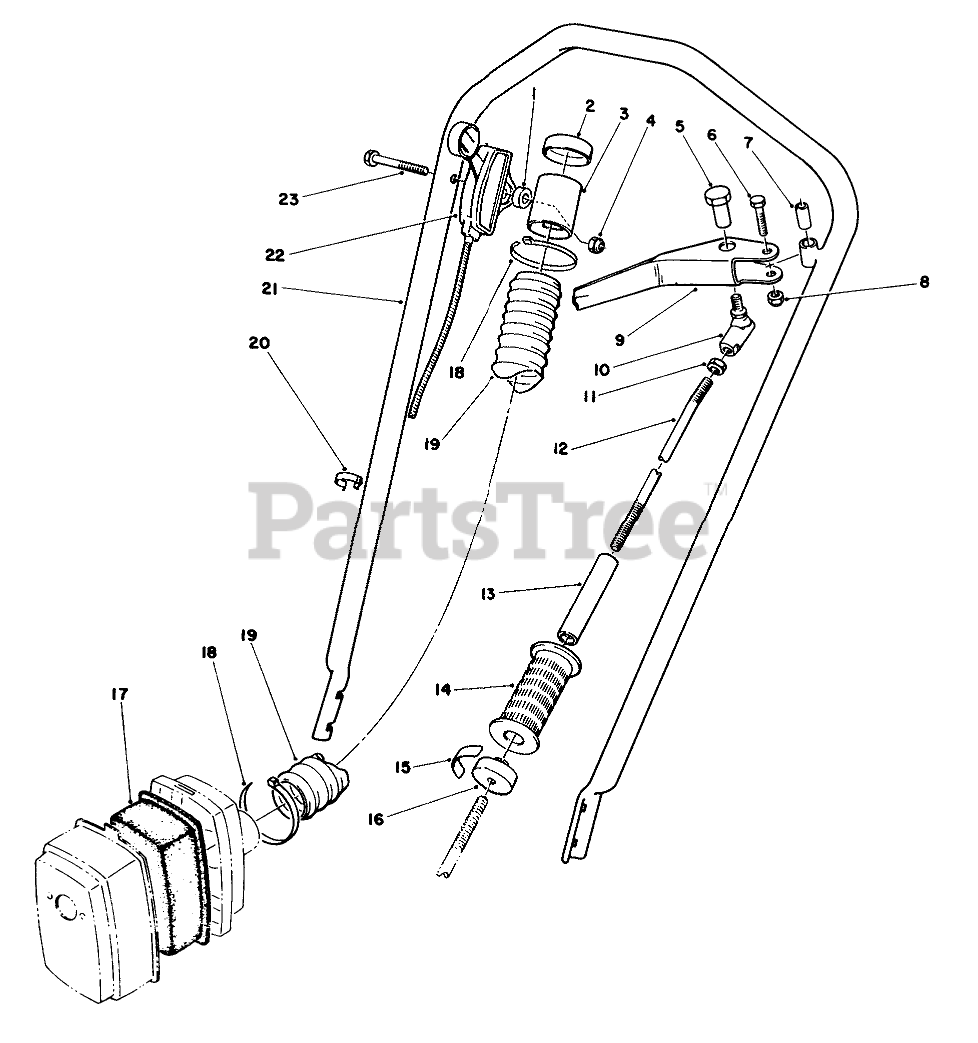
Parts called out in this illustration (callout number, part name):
1	SPACER
2	BLACK CAPLUG
3	AIR CLNR HOSE TIP
4	NUT-HEX
5	CONTROL LEVER BOLT
6	SCREW-HH
7	CONTROL LEVER BSHG
8	NUT-LOCK, NI
9	CLUTCH CONT LEVER B
10	BALL JOINT
11	NUT-HJ
12	UPPER ROD LINKAGE
13	ADJ. TURNBUCKLE O
14	HANDLE GRIP
15	DECAL
16	LOCK KNOB O
17	AIR CLEANER FILTER
18	TIE-CABLE
19	AIR CLEANER HOSE
20	BOWDEN CLIP
21	HANDLE TUBE ASM BO
22	THROTTLE
23	SCREW-HH
